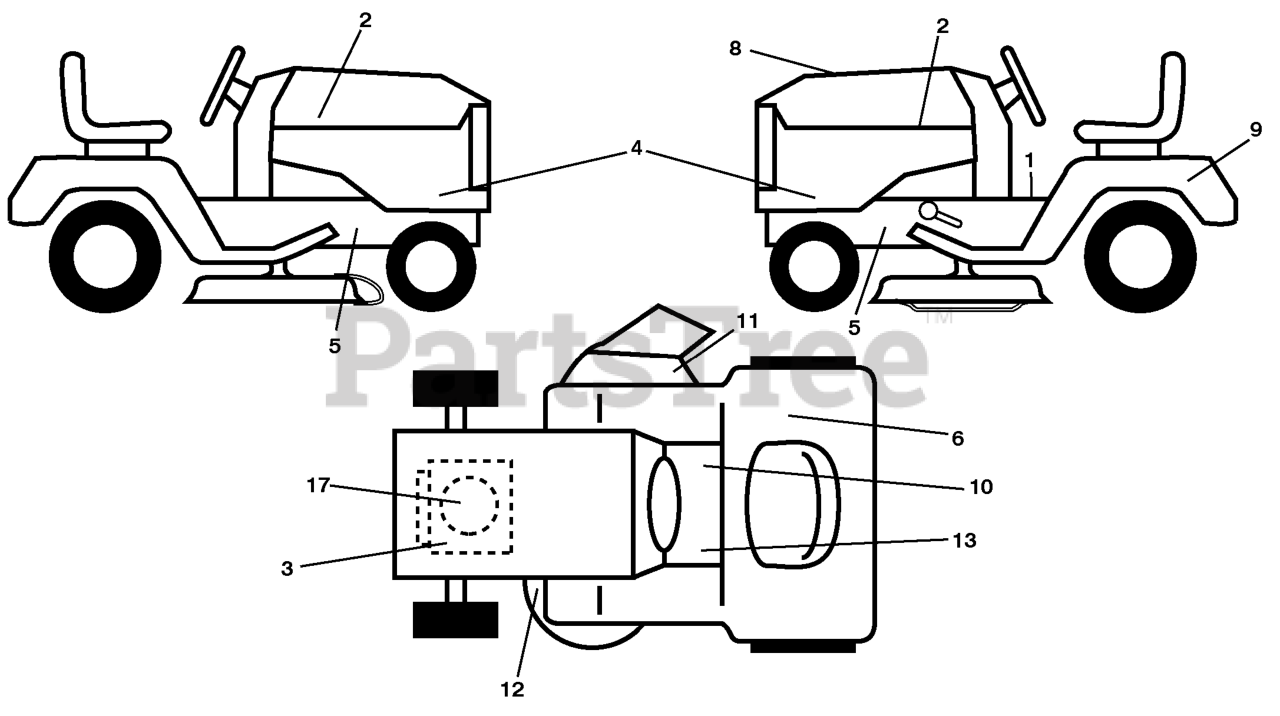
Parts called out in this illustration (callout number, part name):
1	LABEL
2	DECAL.HOOD.LOGO.ORANGE.HUSQVAR
3	DECAL
4	Decal, Hood Panel
6	Decal, Fender 100 DB/CE
8	Decal, Rpl
9	DECAL BTRY SYMBOLS
10	DECAL PARK BRAKE
11	DECAL, WARN. DEFLECT/CTFGR
12	Decal, Mower V-Belt Schematic
13	DECAL
17	Decal, BS Engine
